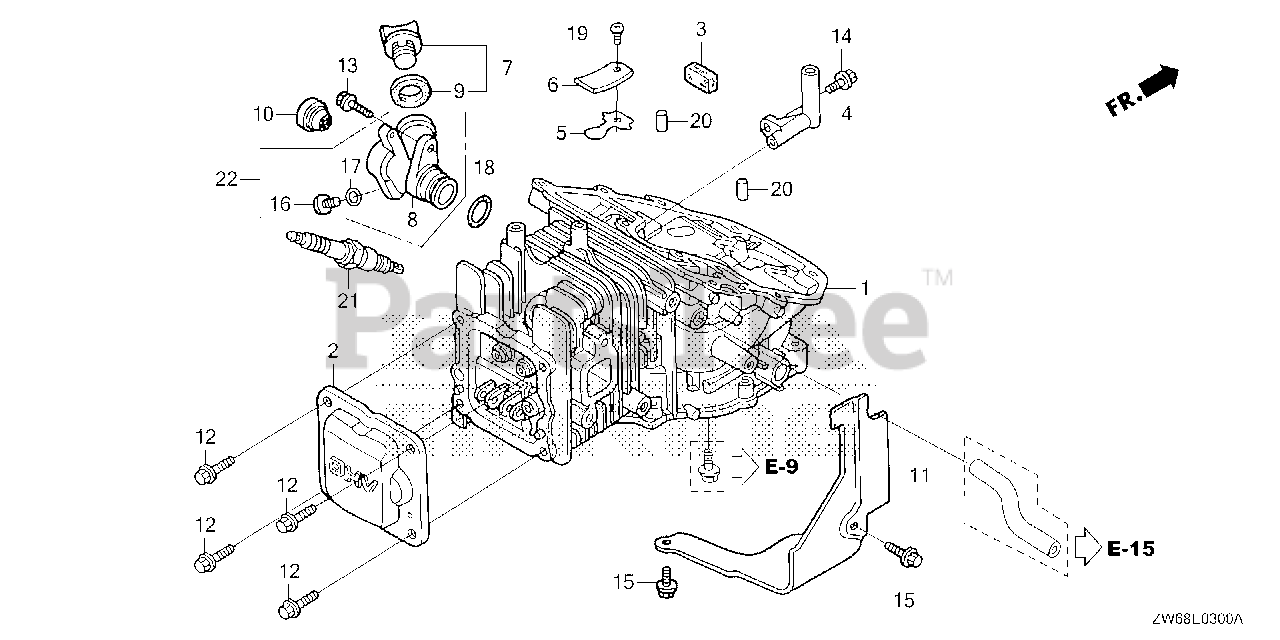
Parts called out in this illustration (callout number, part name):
1	CYLINDER
2	COVER, HEAD *NH105* (MAT BLACK)
3	FILTER, BREATHER
4	PIPE, BREATHER
5	VALVE, OIL OUTLET
6	PLATE, STOPPER
7	CAP ASSY., OIL FILLER
8	EXTENSION, OIL LEVEL FINDER
9	GASKET, OIL FILLER CAP
10	FINDER, OIL LEVEL
11	SHROUD
12	BOLT, FLANGE (5X12) (CT200)
12	BOLT, FLANGE (5X12)
12	BOLT, FLANGE (5X12) (SUS)
13	BOLT, FLANGE (5X16)
14	BOLT (4X10)
15	BOLT, FLANGE (5X10) (CT200)
16	BOLT, OIL CHECK
16	BOLT, OIL CHECK (8X8)
17	GASKET (8MM)
17	O-RING (6.9X1.5)
18	O-RING (22.1X2.2)
19	SCREW, PAN (3X5)
20	ROLLER (6X15)
21	SPARK PLUG (U14FSR-UB)
21	SPARK PLUG (CR4HSB)
22	EXTENSION KIT, OIL LEVEL FINDER
